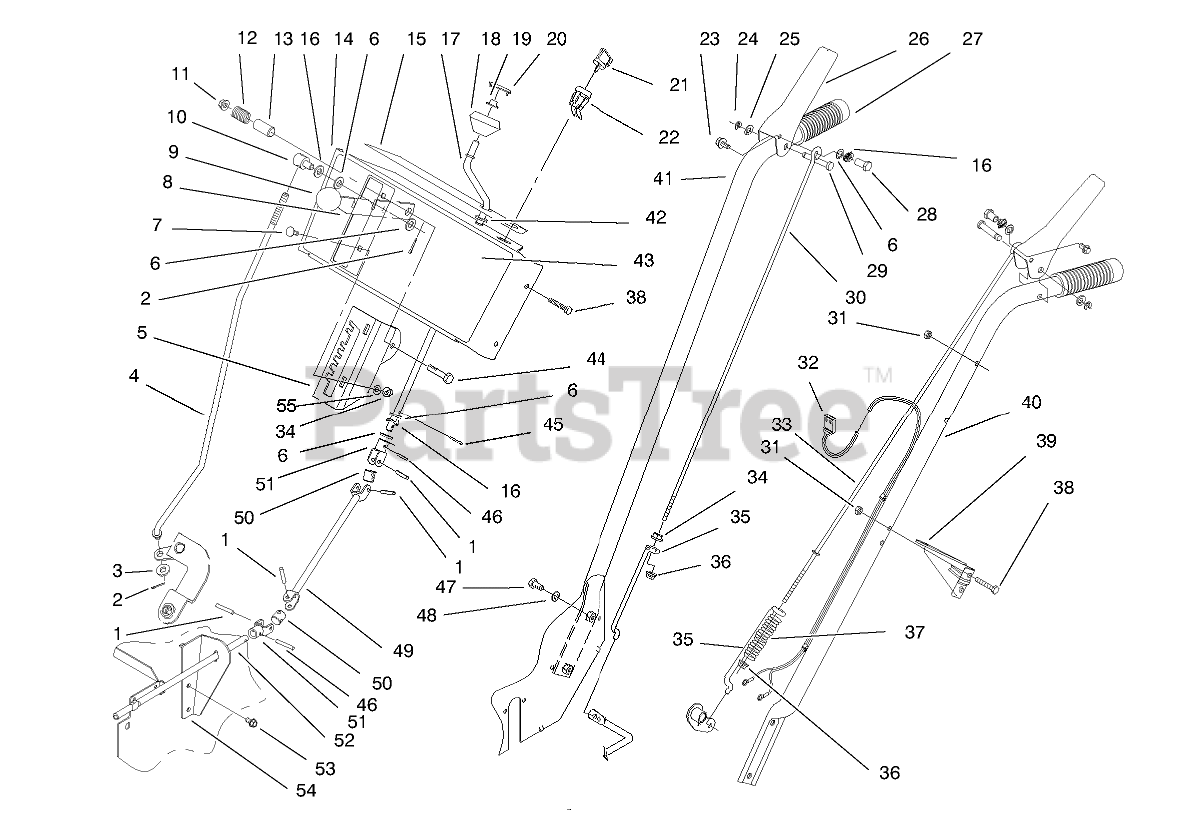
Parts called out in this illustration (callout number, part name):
1	PIN-SPRING
2	PIN-COTTER
3	WASHER-FLAT
4	ROD-SHIFT
5	Mount-Speed Selector
6	WASHER-FLAT
7	SCREW-CARR
8	Speed Selector
10	TRUNNION
11	NUT-HF
13	SPACER
14	Panel-Control
15	Decal-Control Panel Back (Only On: 38084)
15	Decal-Control Panel Back (Only On: 38083)
16	WASHER-SPRING
17	ROD - CHUTE CRANK
18	KNOB-CONTROL, CHUTE
19	RETAINER-PUSH ON
20	COVER-KNOB
21	KEY-IGNITION
22	SWITCH
23	SCREW-HHF
24	RING-CLIP
25	WASHER-PLAIN
26	HANDLE-CONTROL
27	GRIP-HANDLE
28	POST-MOUNTING, LINKAGE
29	PIN-LEVER, CONTROL
30	ROD-UPPER ENGAGE AUGER
31	NUT-LOCK, NI
32	WIRE HARNESS
33	ROD-UPPER TRACTION
34	NUT-HF
35	ROD-LOWER TRACTION
36	NUT-HHF
37	SPRING
38	SCREW-HH
39	Bracket-Chute Crank Upper
40	Handle-Left (Only On: 38083)
40	Handle-Left (Only On: 38084)
41	Handle-Right (Only On: 38083)
41	Handle-Right (Only On: 38084)
42	Bushing
43	DECAL - CONTROL PANEL
44	SCREW-HH
45	PIN-COTTER
46	PIN-SPRING
47	SCREW-HWHTF
48	WASHER-BELLEVILLE
49	WA - CLEVIS ROD
50	BLOCK - PIVOT
51	WA - CLEVIS MOUNT
52	ROD - CHUTE CONTROL
53	SCREW-HWH
54	Bracket-Crank Rod Lower
55	WASHER-FLAT
